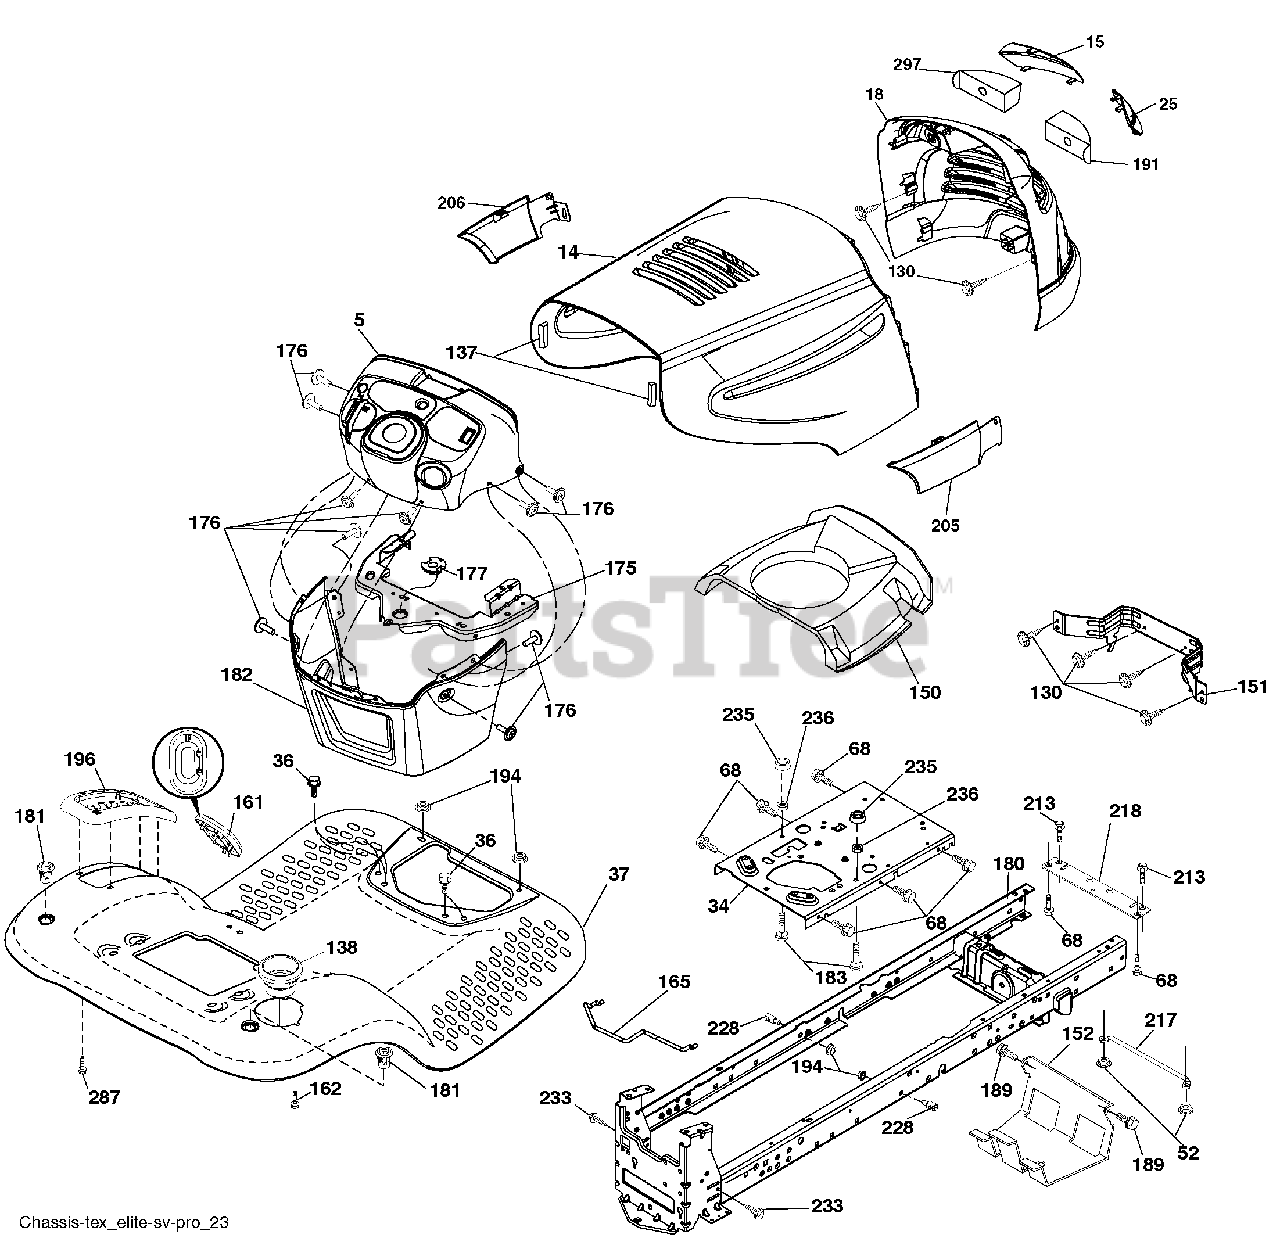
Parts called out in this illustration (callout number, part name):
2	Drawbar
14	Hood
15	Lens Grille LH
18	Grille
25	Lens Grille RH
34	Plate Engine
36	Screw 5/16-18 x 3/4
52	Nut Lock 5/16-18
68	Screw THDROL 5/16-18 x 1/2
130	Screw #10 x 0.750 BOS Thread
137	Bumper Hood
138	Cupholder
150	Duct Heat Hood
151	Bracket Pivot
152	Shield Browning/Debris
161	Window Fuel
162	Screw Hex Wsh Hi-Lo 1/4 x 1/2 unc
165	Bracket Support Tank
175	Crossmember
176	Screw 10-24 x 5/8 Wshd Qdrx
177	Bushing Steering
180	Chassis
181	Bushing Mtg. Fender Crgo.
182	Dash Lower
183	Bolt 5/16-18 x 1-1/4
189	Screw 5/16-18 x 3/4
191	Insert Reflective RH
194	Nut Lock Hex Flange 5/16-18
196	Console Asm. Deck Lift
213	Bolt 5/16-18 x 3/4
217	Rod Pivot Chassis
218	X-Piece Hood Stop
228	Stud Fastener
233	Bolt Shoulder
235	Spacer Fender
236	Nut Center lock 5/16-18 unc
287	Screw Hex Washead 1/4-20 x 3/8
297	Insert Reflective LH
